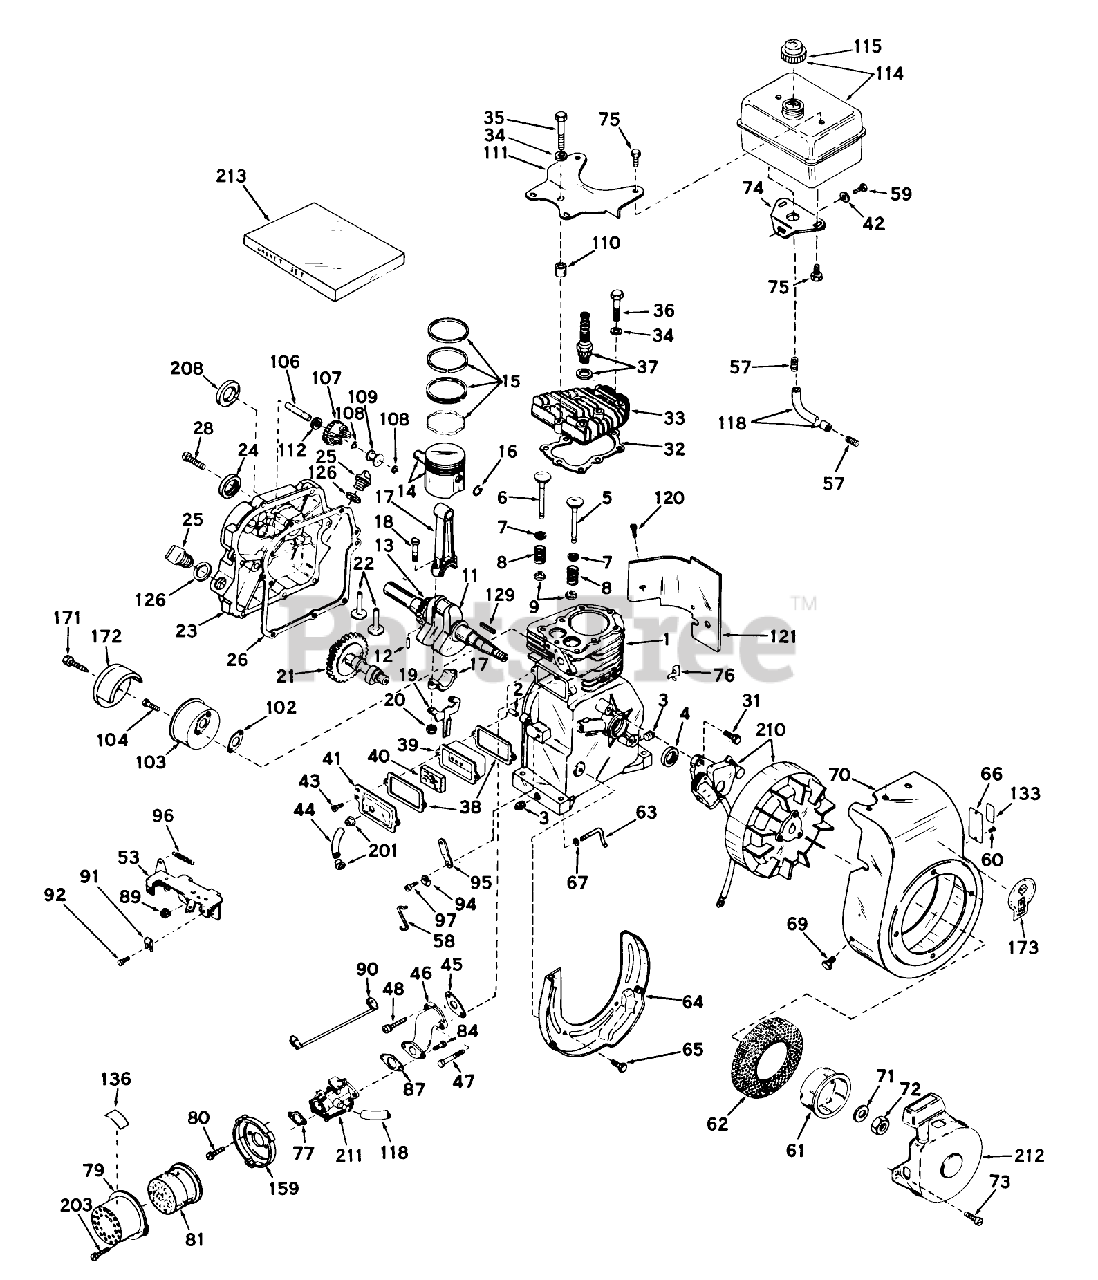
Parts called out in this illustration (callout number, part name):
1	Cylinder Assy.(Incl. Nos.2, 3 4)
2	Pin-Dowel
3	Plug-Drain, Oil (SQH 1/4-18)
4	OIL SEAL
5	Valve, Intake (Incl. Ref. #38, 39 40) (Std.)
5	Valve, Intake(1/32"overs.)(Incl. Ref. 8, 9 10)
6	Valve, Exhaust (Standard)(Incl. Ref. 8, 9 10)
6	Valve, Exhaust (1/32" Overs.(Incl. Ref. 8, 9 10)
7	Cap-Upper Valve Spring
8	Spring-Valve
9	Cap-Valve, Spring
11	Crankshaft Assy. (Incl. Nos. 12 13)
12	Pin, Groove
13	Gear, Crankshaft
14	Piston Pin Assy. (Standard) (Incl. 2 of No. 16)
14	Piston Pin Assy. (.010 Oversize) (Incl. 2 of No. 16)
14	Piston Pin Assy. (.020 Over size)(Incl. 2 of No. 16)
15	Ring Set, Piston (Std.)
15	Ring Set, Piston (.010 o.s.)
15	Ring Set, Piston (.020 o.s.)
16	Ring-Retaining, Piston Pin
17	Rod Assy., Connecting (Incl. Ref. #17)
18	Bolt, Connecting
19	53020/22 GIL.HYDRO
20	LOCKNUT
21	Camshaft, BCR, Extended
22	Lifter-Valve
23	Cover, Cylinder (Incl. Nos. 24, 25, 26, 106, 126 208)
24	Seal, Oil
25	Plug-Fill, Oil
26	Gasket-Cylinder Cover
28	Screw
31	Screw
32	Gasket-Cylinder Head
33	CYLINDER HEAD
34	Washer
35	Screw Hex Hd. Cap
36	Screw
37	SPARK PLUG
38	Gasket-Breather
39	Body-Breather
40	Element, Breather
41	Gasket-Gear Case
42	Washer
43	Screw
44	Breather Tube
45	Gasket-Intake
46	Pipe, Intake
47	Screw
48	Screw
53	Bracket Control
57	Spring, Coil
58	Jet-Main
59	Screw (1/4-20x19/32)
60	DRIVE STUD
61	Starter Cup
62	Screen, Air
63	Rod-Governor
64	Baffle, Blower Hsg.
65	Screw (1/4-20x19/32)
66	IDENTIFICATION PLATE
67	Washer-Flat
69	Screw
70	Housing,Blower
71	Washer
72	Hex Nut
73	Screw
74	Bracket, Fuel Tank Lower
75	Screw (1/4-15x7/8)
76	Clip-Wire
77	Gasket
79	Body
80	Screw (10-32 x 1/2)
81	AIRCLEANER
87	Gasket
89	Nut and Lock Washer (1/4-28)
90	Wire, Ground
91	Conduit
92	Screw (10-32 x 3/8)
94	Clamp-Lever, Governor
95	Lever-Governor
96	Spring-Extension
97	Screw
102	Gasket Exhaust
103	Muffler
104	Screw
106	Shaft-Governor
107	Governor Gear ASM
108	Ring-Retaining
109	Spool-Governor
110	pacer
111	Bracket, Fuel tank
112	Washer-Flat
114	53023/VAR.10/16HP O
115	Cap-Fuel
118	Line-Fuel
120	Screw
121	Extension-Blower
126	Gasket
129	Key Flywheel
133	Decal, Instruction
136	DECAL, AIRCLEANER
159	BRACKET, AIRCLEANER
171	Screw, Muffler
172	Cover-Muffler
173	Decal, Name H.P.
201	GROMMET
203	Screw
208	Seal, Oil
210	Magneto
211	Carburetor
212	Starter, Rewind
213	Gasket Set
